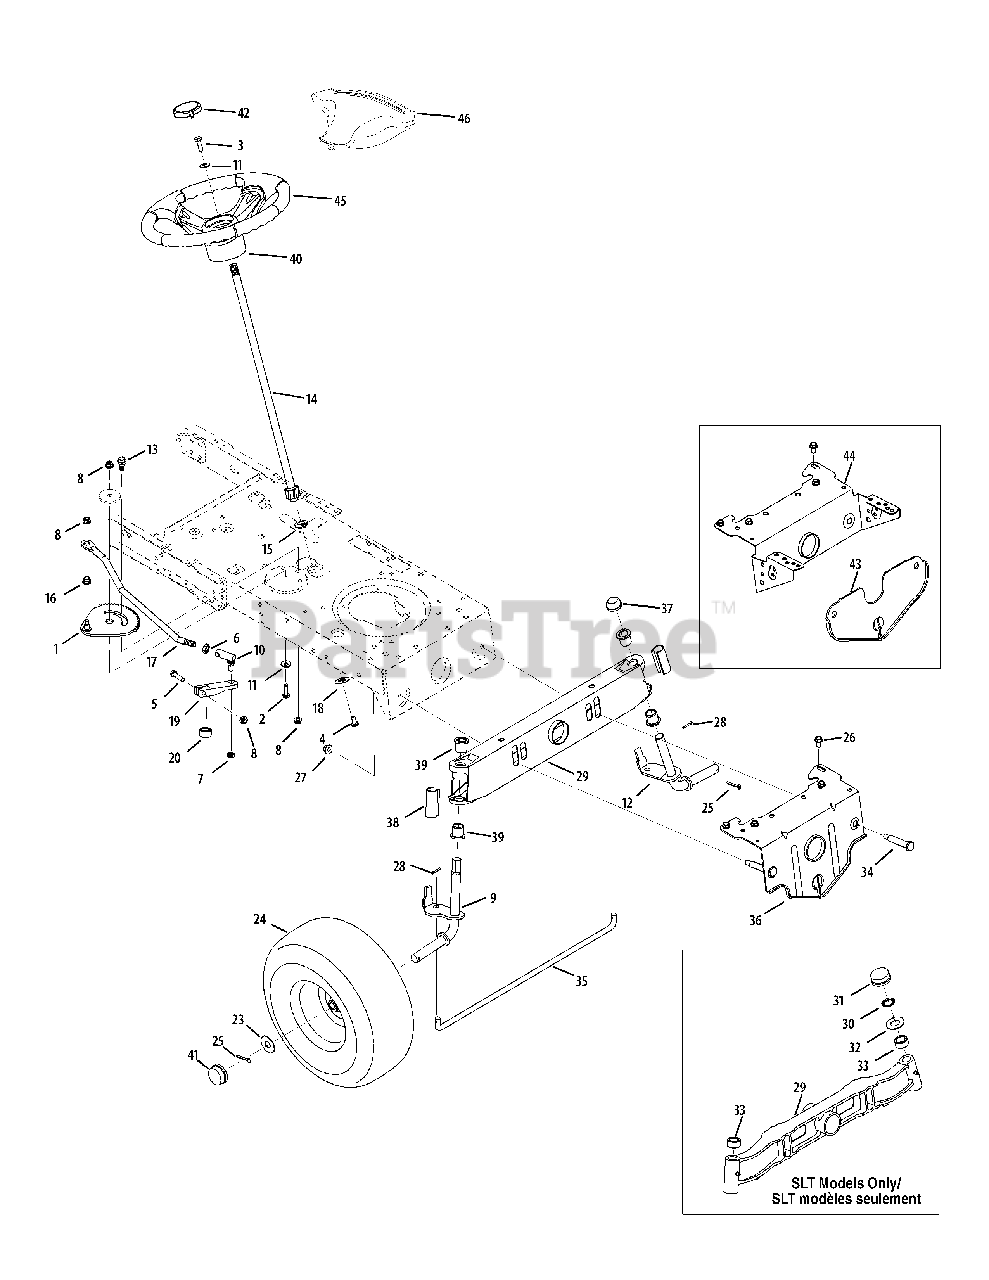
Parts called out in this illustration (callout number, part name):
1	Steering Gear Assembly
2	Hex Hd. Cap Screw 3/8-16 x 1,00 Gr. 5
3	Hex Screw 5/16-18 x 1.00 Spe cial
4	Ma chine Screw 5/16-18 x .75
5	Hex Screw 5/16-18 x 1.75" Lg.
6	Hex Jam Nut 7/16-20
7	Hex Cent-L Nut 3/8-24 Gr. B
8	Flange Locknut 5/16-18 Gr. F, Nylon
9	Axle Assembly, RH
10	Ball Joint, 7/16 - 20
11	Cupped Washer .345 ID x .88 OD x .060
12	Axle Assembly, LH
13	Shoulder Screw .435 x .3485, 5/16-18
14	Steering Shaft, 5/8 Spline x 21.86
15	Hex Flange Bearing 5/8
16	Plastic Bushing .375 ID x .5
17	Steering Drag Link
18	Cap, 1.25 x .16
19	Steering Block
20	Spacer .710 ID x .125 OD x .56
22	Shoulder Spacer
23	Flat Washer .781 ID x 1.59 OD Special
25	Cotter Pin 5/32 x 1.25
26	S-Tapp Screw 5/16-18 x .75
27	Flange Lock-Nut 3/8-16 Gr. F, Nylon
28	Cotter Pin 1/8" Dia x .75
29	Pivot Bar (cast)
30	Push Nut 3/4"
32	Flat Washer .78 x 1.59 x .060
33	Spacer .71 x .125 x .56
34	Shoulder Screw .500 x 2.380, 3/8-16
36	Pivot Bar Bracket
37	Push Cap, .750
38	Axle End Cap, Stan dard
39	Flange Bearing .760 ID x .937 OD
40	Steering Wheel, Standard Grip
41	Plastic Hub Cap
42	Steering Wheel Cap (w/o logo)
42	Steering Wheel Cap (spig logo)
42	Cap Steering Wheel (Troy Bilt)
45	Steering Wheel
45	Steering Wheel, Soft Grip
46	Steering Wheel Cover (MTD)
